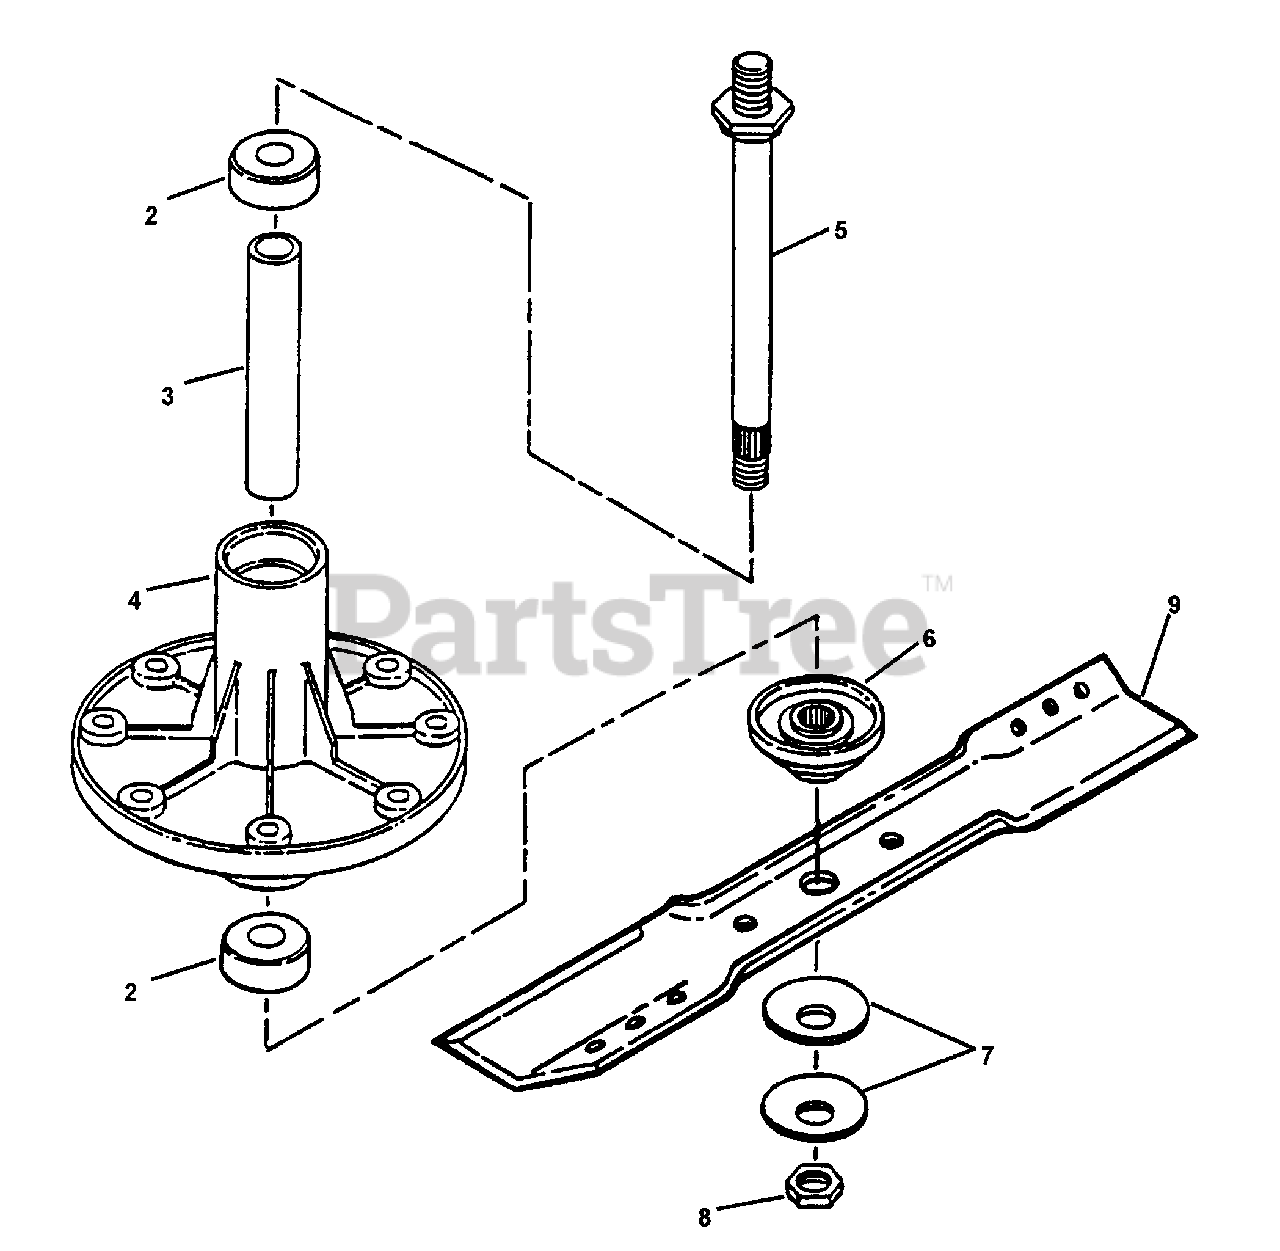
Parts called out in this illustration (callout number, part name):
2	BEARING, Spindle
3	SPACER, Spindle Housing
4	HOUSING, Spindle
5	SPINDLE (7.019" Long)
6	SPACER, Blade
7	WASHER, Belleville, 19/32" I.D. x 1-3/4" O.D.
8	NUT, 9/16-18 Hex Jam
9	BLADE, 19.64
